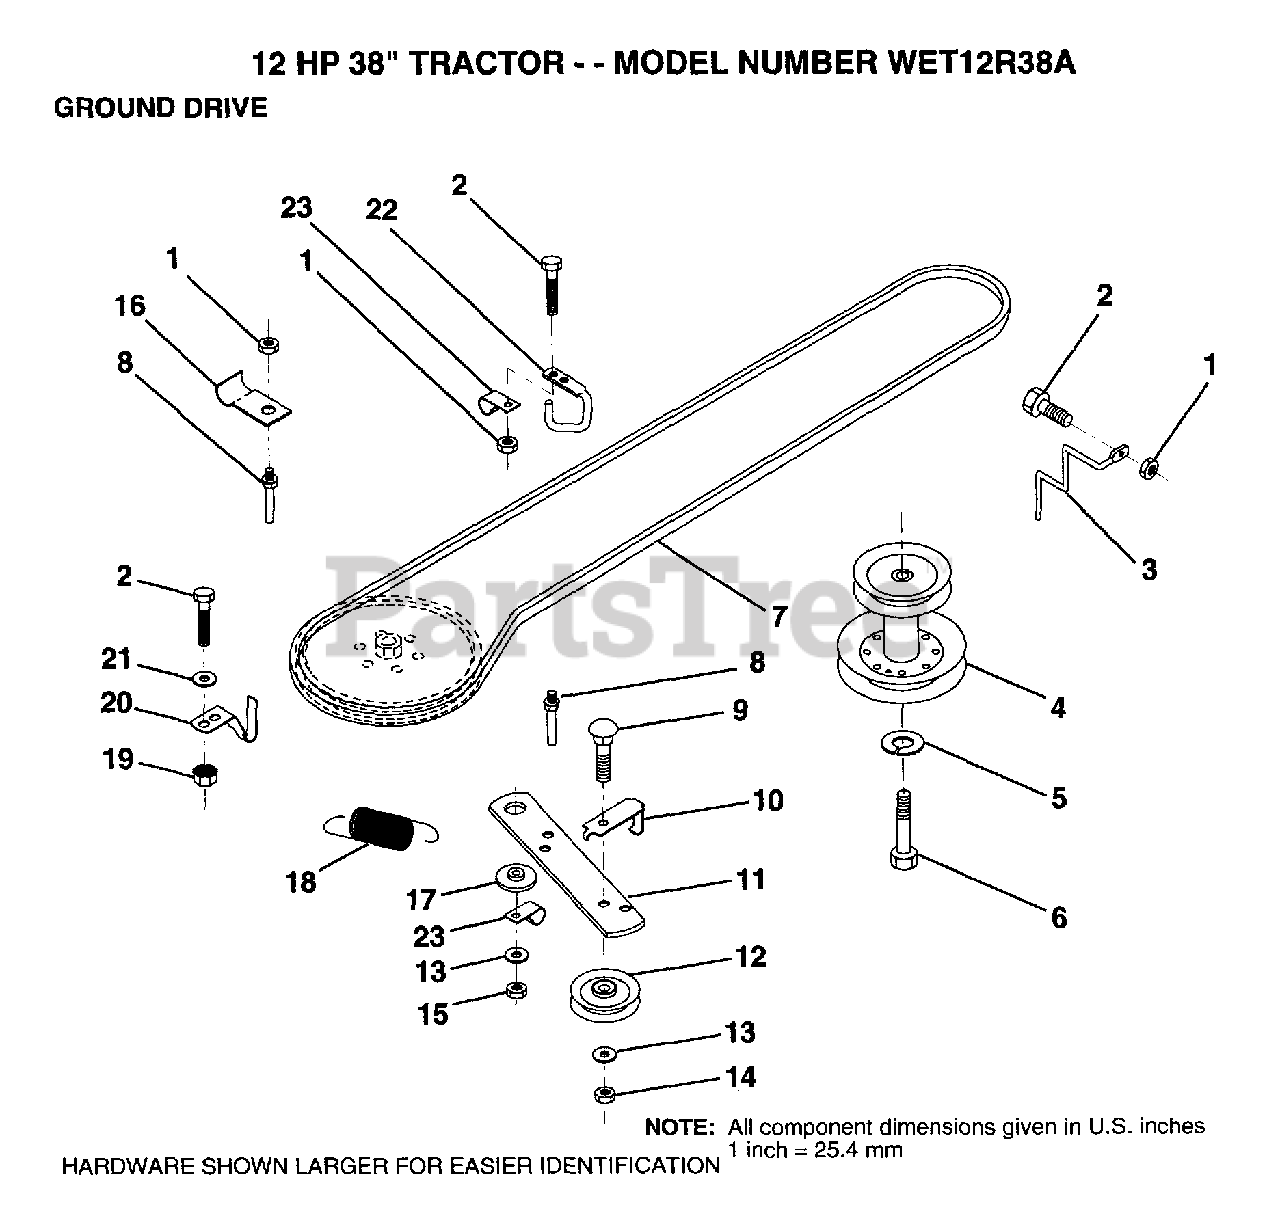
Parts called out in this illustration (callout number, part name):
2	BOLT
3	KEEPER MWR DR BLT
5	LOCKWASHER
6	BOLT
7	BELT
8	"KEEPER,DRIVE BELT"
9	BOLT
10	"KEEP,IDLER DR BEL"
12	PULLEY IDLER
13	WASHER
14	LOCKNUT
16	"CLIP,INSULATOR"
17	SPACER RETAINER
20	"KEEPER,DR BELT "
21	WASHER
22	"KEEPER,FRA DR BEL"
23	CLIP INSULATOR
